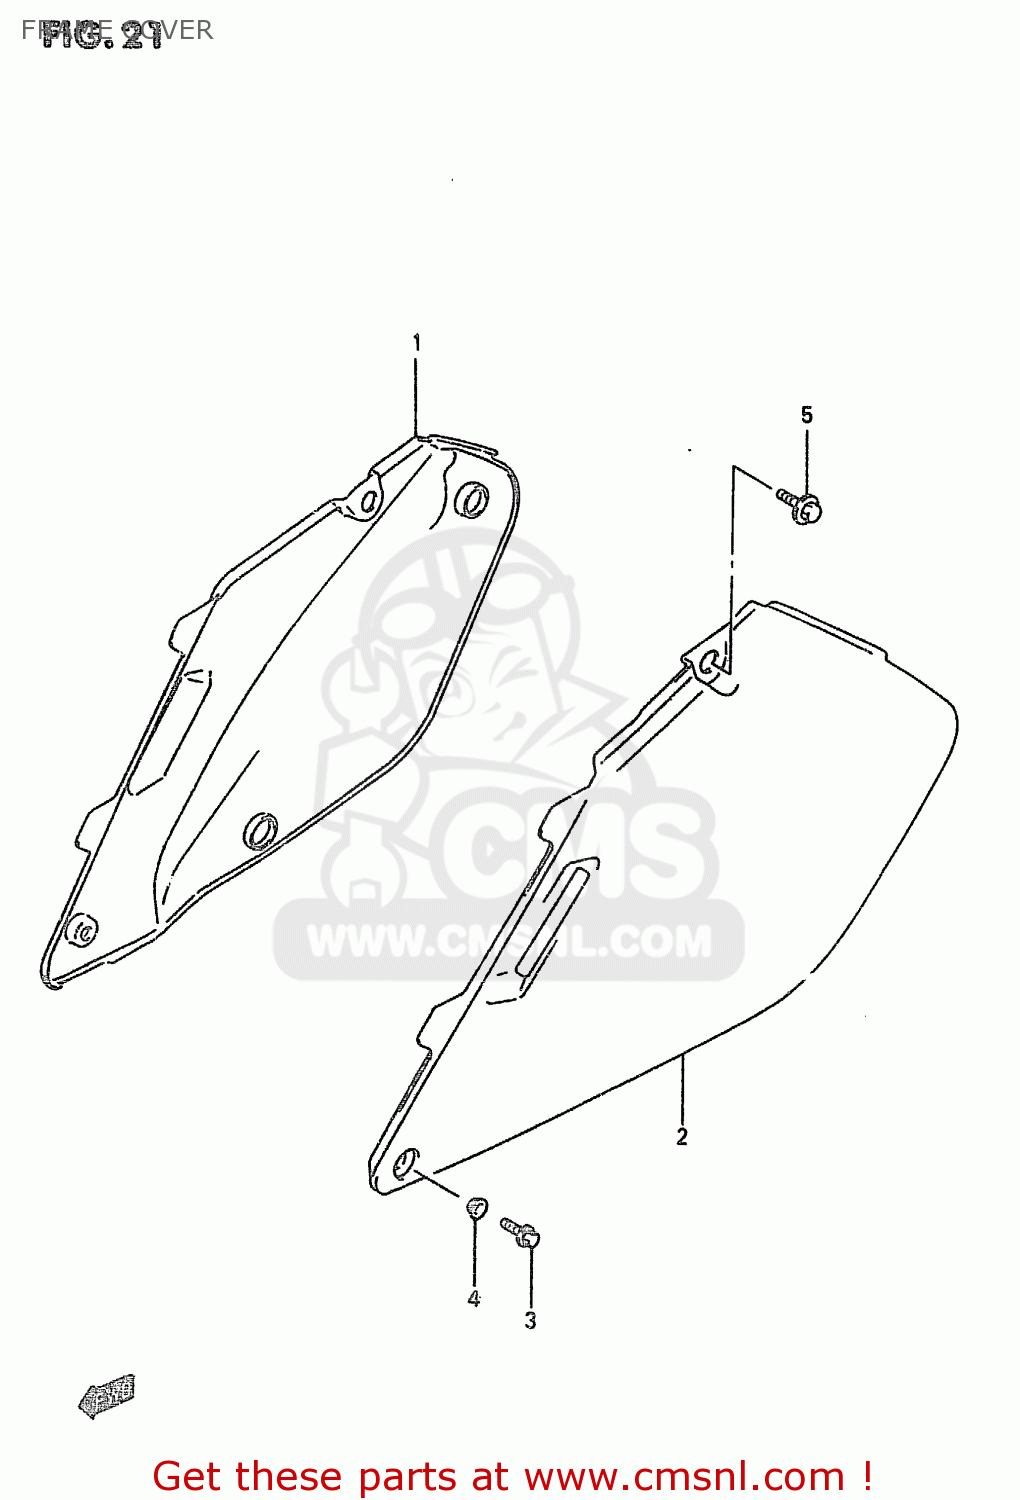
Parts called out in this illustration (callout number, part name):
1	COVER,FRAME,R(WHITE)
2	COVER,FRAME,LEFT
3	BOLT
4	WASHER
5	BOLT(6X16)
